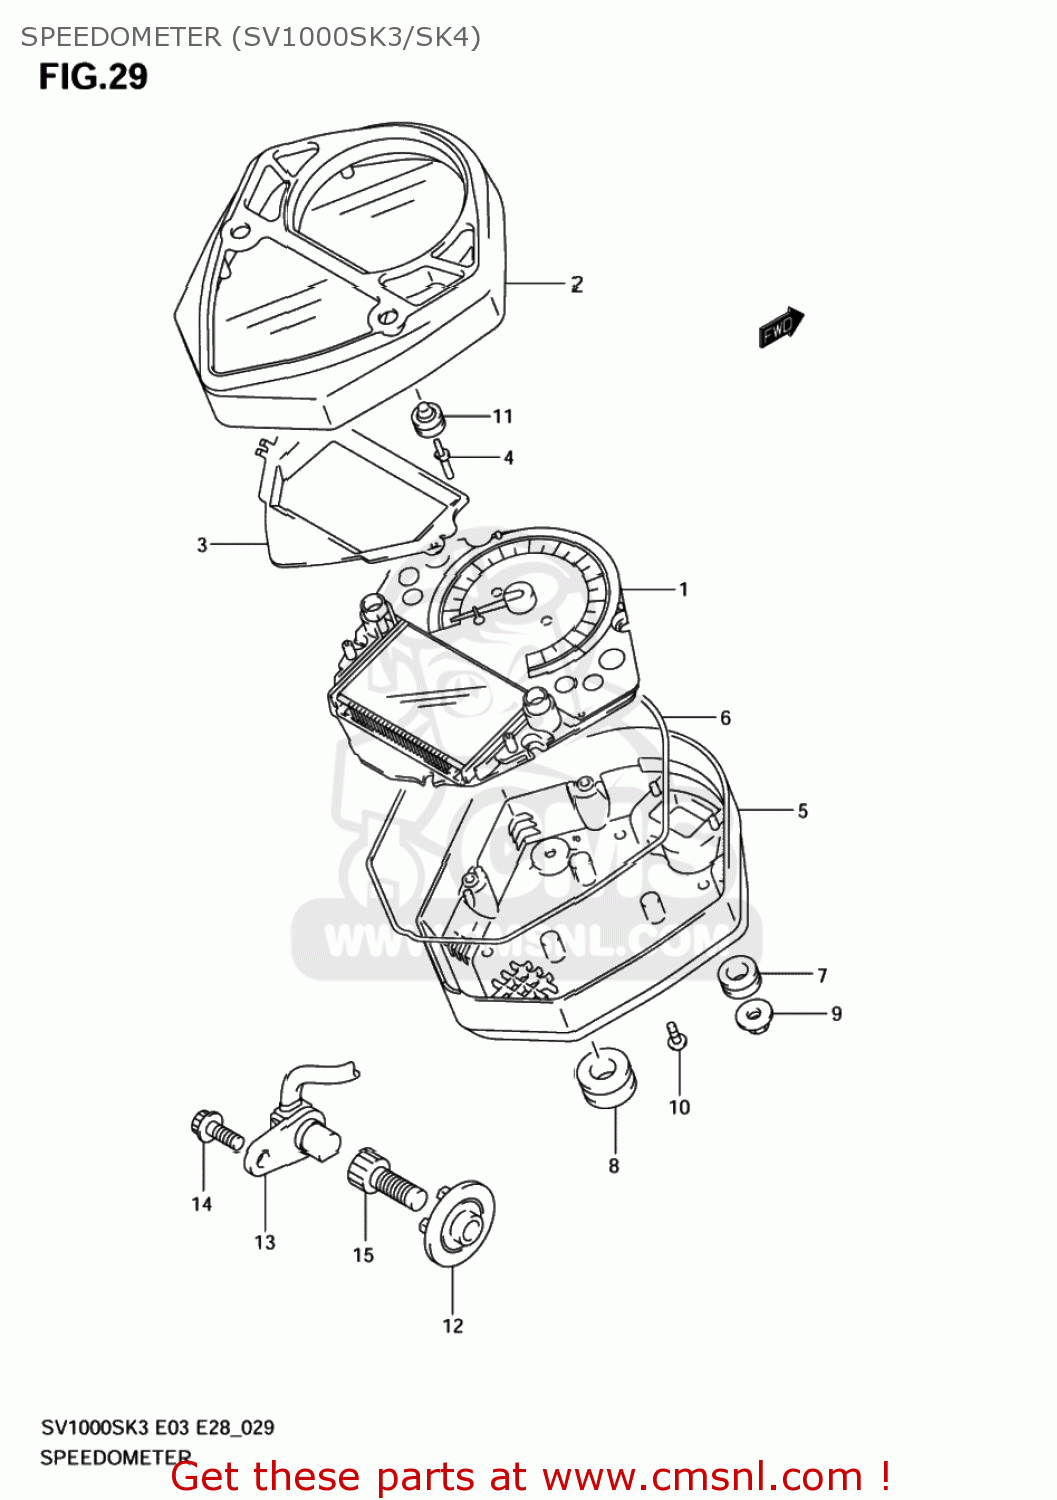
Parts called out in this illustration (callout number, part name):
1	SPEEDOMETER
2	CASE,SPEEDOMETER UPR
3	PLATE,SPEEDOMETER
4	KNOB,SPEEDOMETER
5	CASE,SPEEDOMETER LWR
6	GASKET,METER CASE (NAS)
7	CUSHION
8	CUSHION
9	NUT
10	SCREW,SPEEDOMETER
11	COVER,SPEEDOMETER KNOB
12	ROTOR,SPEED
13	SENSOR,SPEED
14	BOLT
15	BOLT
